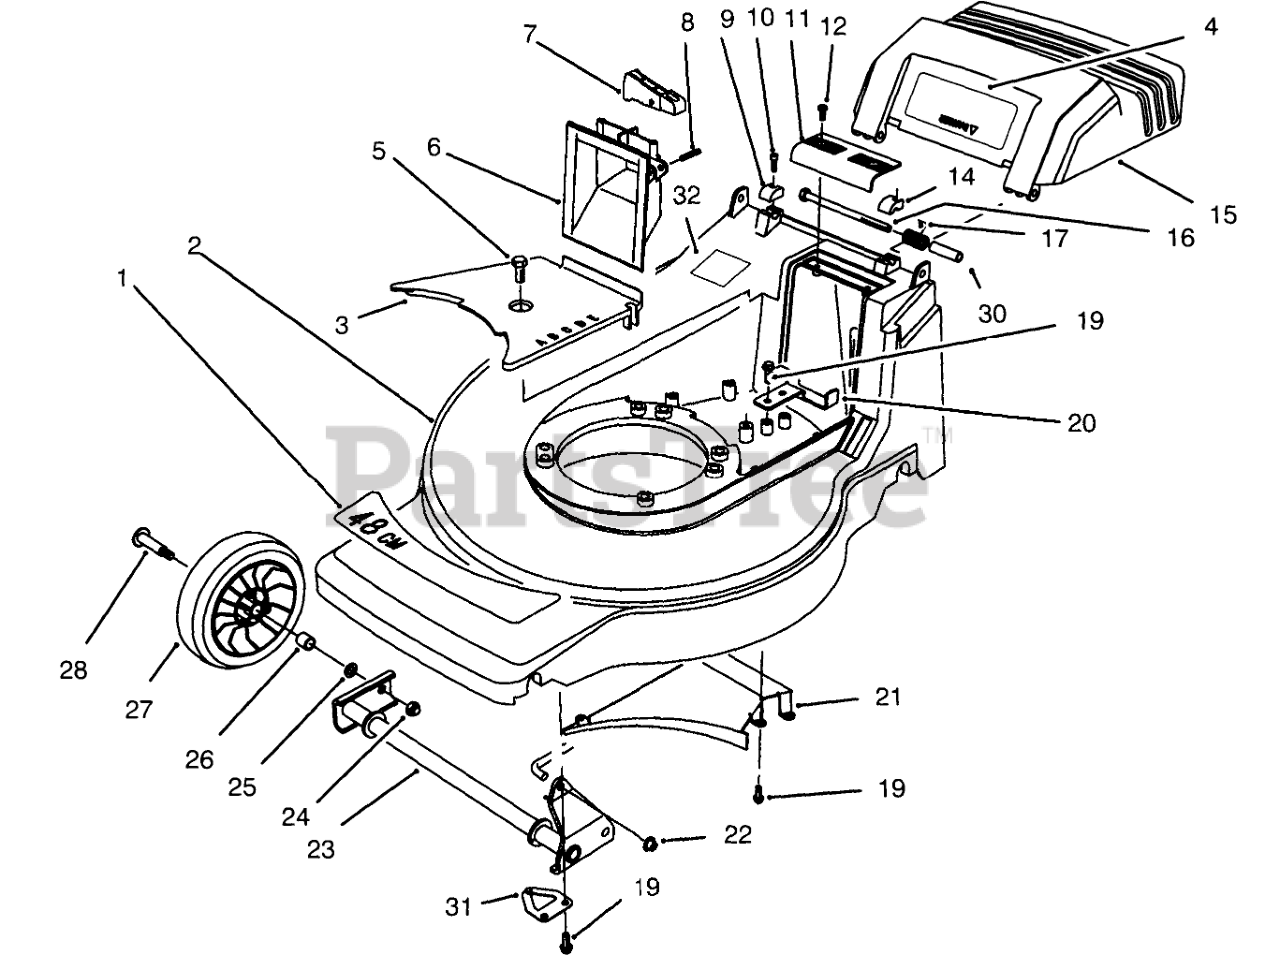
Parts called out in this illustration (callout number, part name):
1	DECAL - DECK 48 CM
2	HOUSING W/DECAL RED
3	BELT COVER
4	DECAL-DANGER
5	SCREW-HWHTF
6	GRIP - LOWER
7	TRIGGER - HOC
8	PIN-SPIRAL
9	CAP-HINGE BOLT, RH
10	SCREW-HSH
11	GRIP-UPPER
12	SCREW-PPH, PLASTITE
14	CAP-HINGE BOLT, LH
15	Door Discharge
16	SCREW-HH
17	SPRING-DOOR
19	SCREW-HWH
20	REAR BELT GUIDE
21	Ramp-Discharge
22	NUT-PUSH
23	FRONT PIVOT WA
24	NUT-HEX
25	WASHER
26	BUSHING
27	Wheel & Tire Assembly(Incl Ref. #26)
28	BOLT-WHEEL
30	SPACER-DOOR
31	SHAFT RETAINER ASM
32	Decal-Noise
